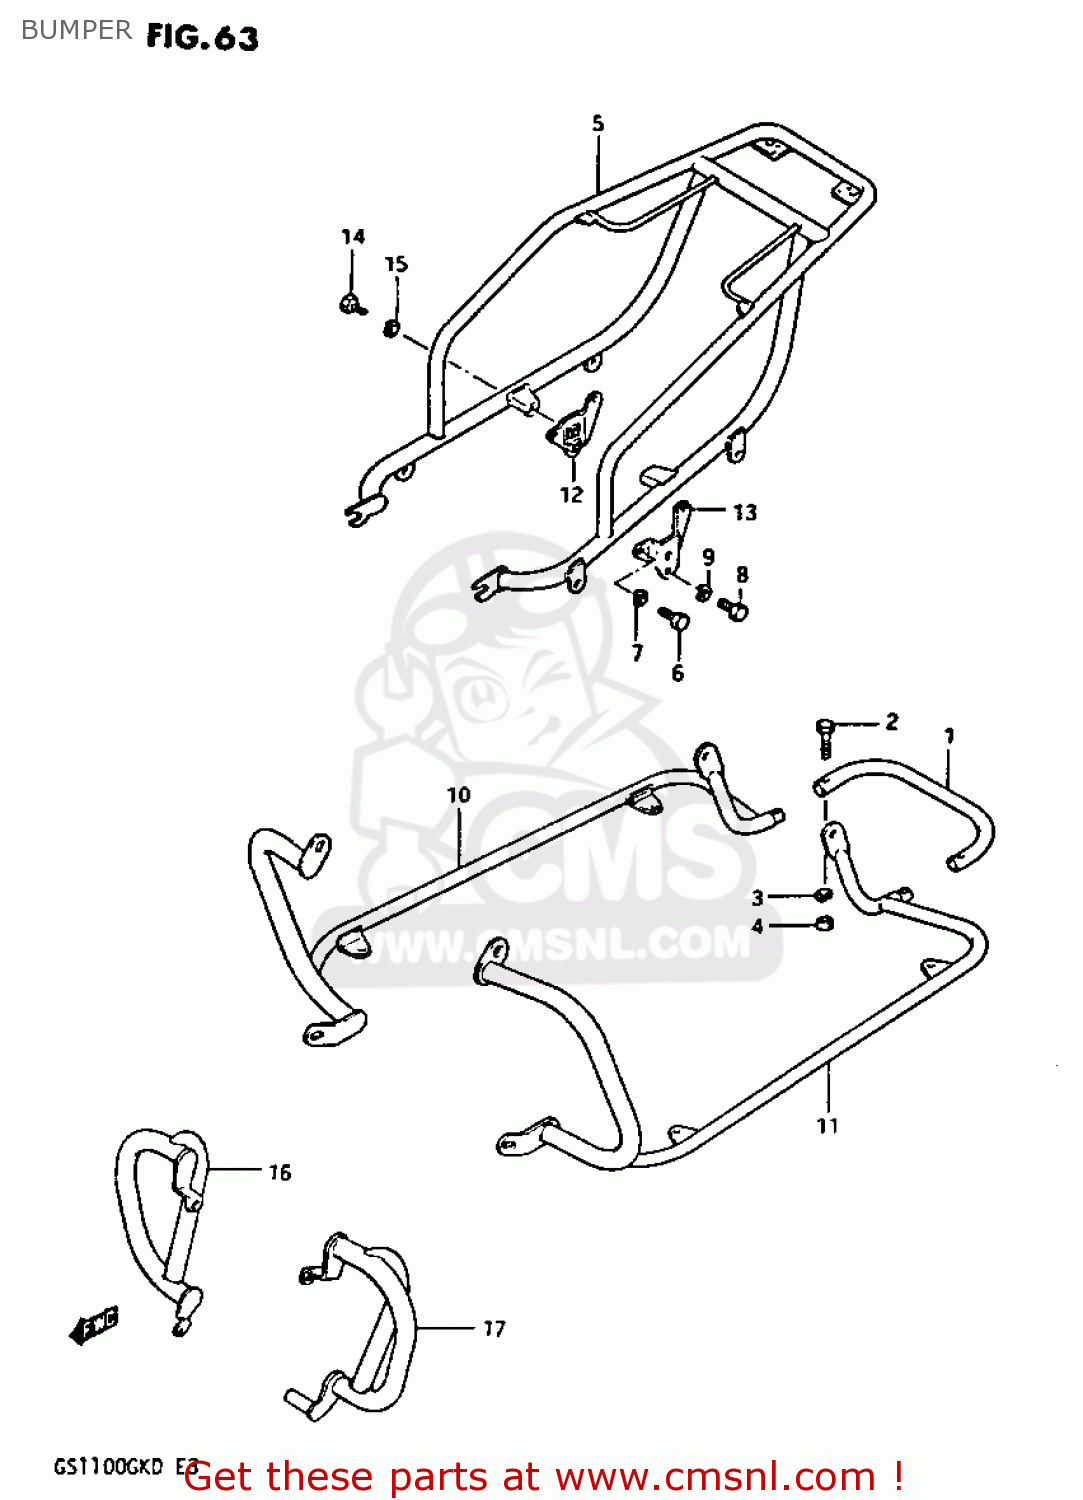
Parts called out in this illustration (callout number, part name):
1	BUMPER,REAR
2	BOLT
3	WASHER,LOCK
4	NUT
5	CARRIER TRAVEL TRUNK
6	BOLT
7	LOCK WASHER
8	BOLT
9	LOCK WASHER
10	CARRIER,REAR SIDE,RIGHT
11	CARRIER,REAR SIDE,LEFT
12	BRKT COMP RR CARR R
13	BRKT COMP RR CARR L
14	BOLT
15	LOCK WASHER
16	COVER COMP,ACCESSORY B
17	ACCESSORY BAR,CASE LEFT
